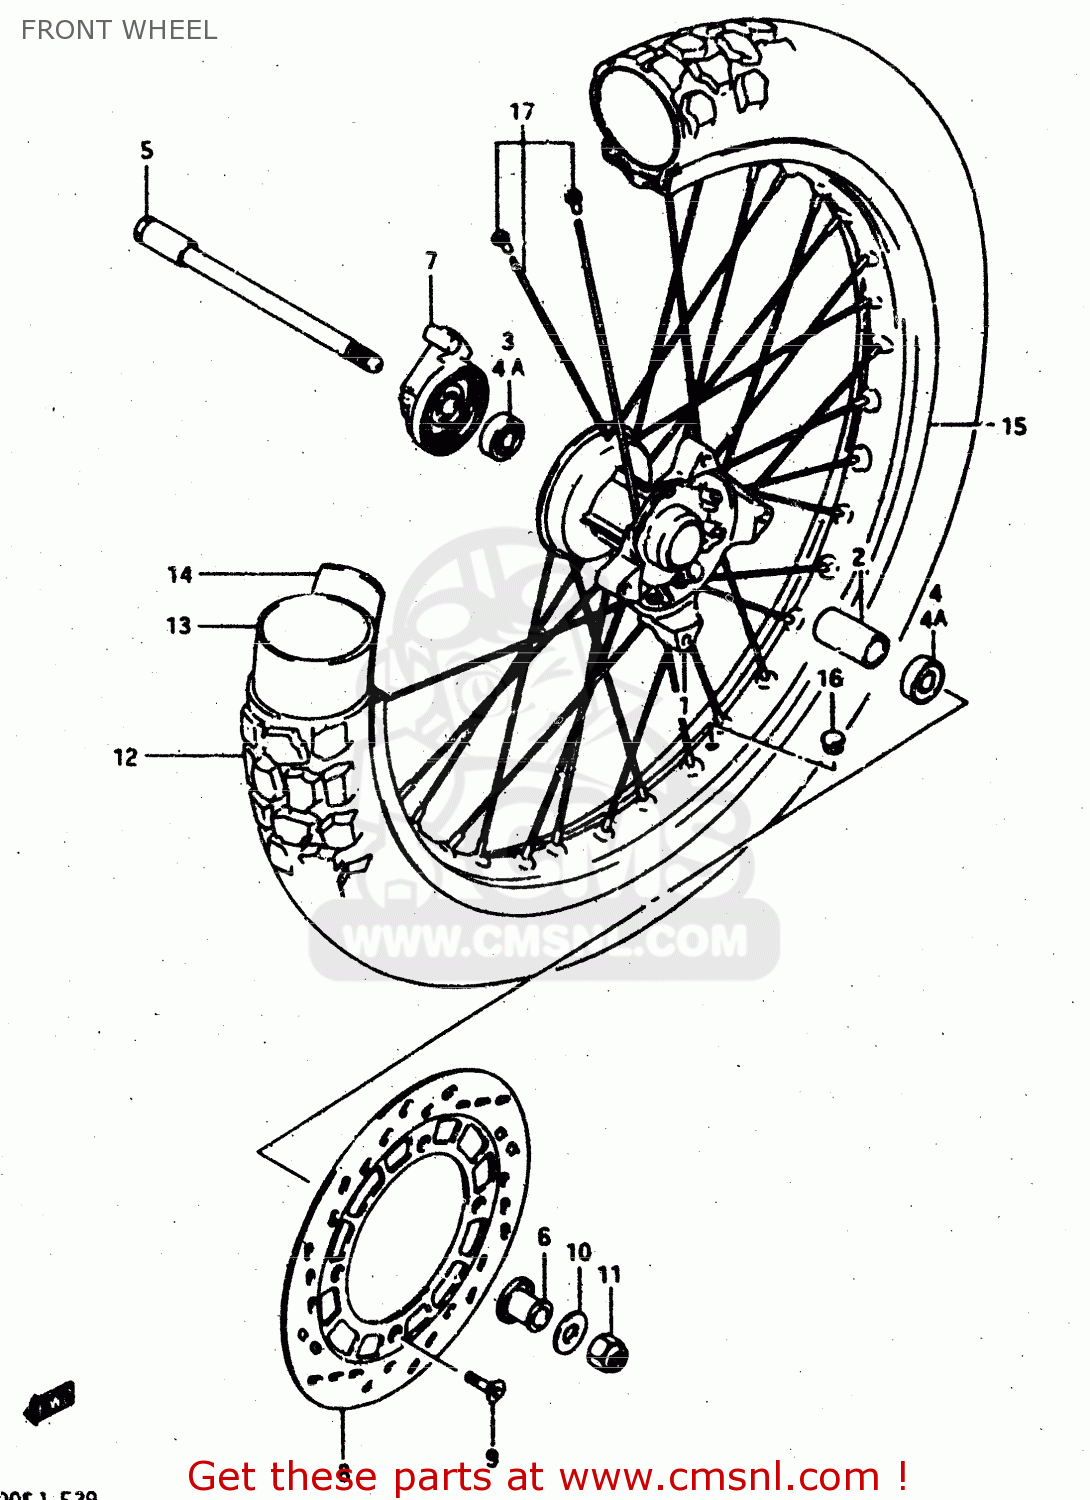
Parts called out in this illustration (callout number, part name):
1	HUB,FRONT
2	SPACER(15.3X21.7X56)
3	BEARING
4	BEARING
4A	BEARING
5	AXLE,FRONT
6	SPACER,FRONT AXLE,LEFT
7	BOX ASSEMBLY,SPEEDOMETER GEAR
8	DISC,FR BRAKE
9	BOLT,BRAKE DISC
10	WASHER
11	NUT
12	TIRE 100/80-21
13	TUBE,INNER
14	PROTECTOR,WHEEL,INNER
15	RIM,FRONT WHEEL
16	CAP(OD:12)
17	SPOKE SET,FRONT
